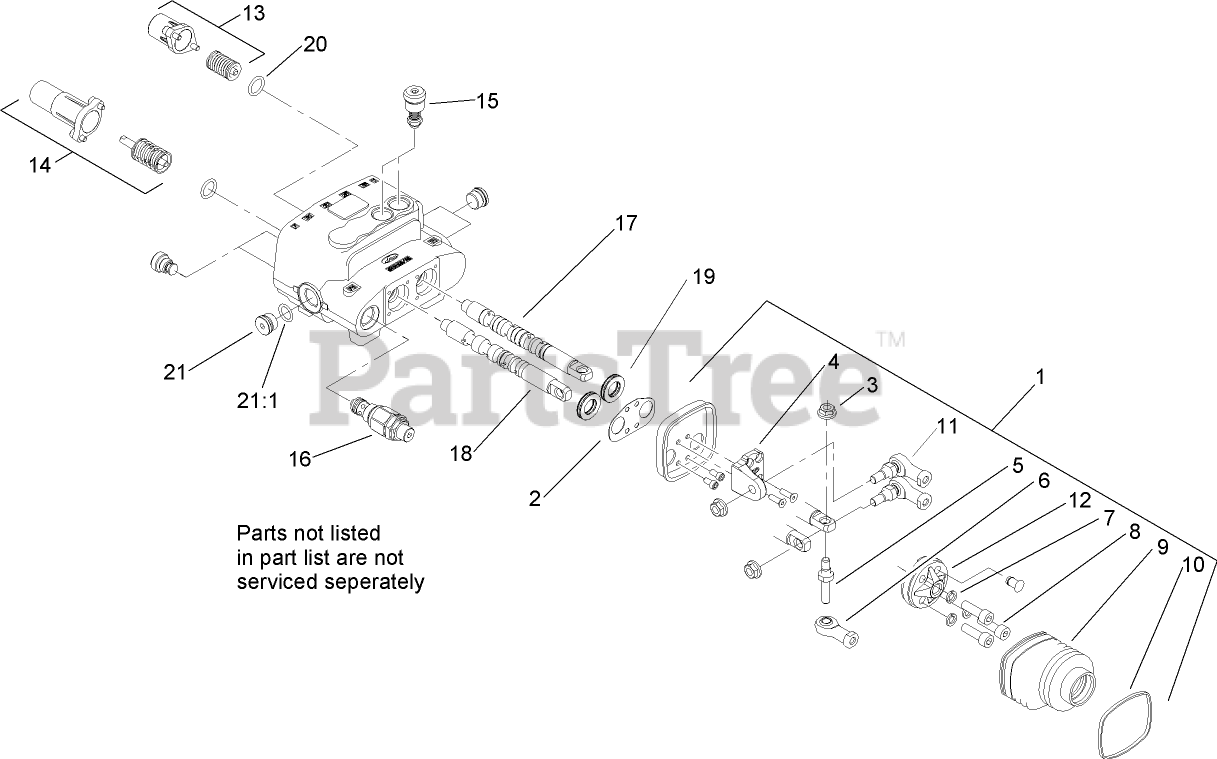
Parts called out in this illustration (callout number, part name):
1	JOYSTICK KIT
2	SEAL-JOYSTICK
4	PIVOT-JOYSTICK
5	PIN-JOYSTICK
6	END-ROD
7	WASHER-LOCK, SPRING
8	SCREW-HSH
9	BELLOW-RUBBER
10	TIE-CABLE
11	JOINT-JOYSTICK
12	HOLDER-ARTICULATED
13	VALVE SPRING KIT
14	DETENT SPRING KIT
15	VALVE-RELIEF
16	VALVE-RELIEF, MAIN
17	SPOOL-VALVE
18	SPOOL-VALVE
19	SEAL-VALVE, SPOOL
20	SEAL-VALVE
21	PLUG-HEX
21:1	O-RING
